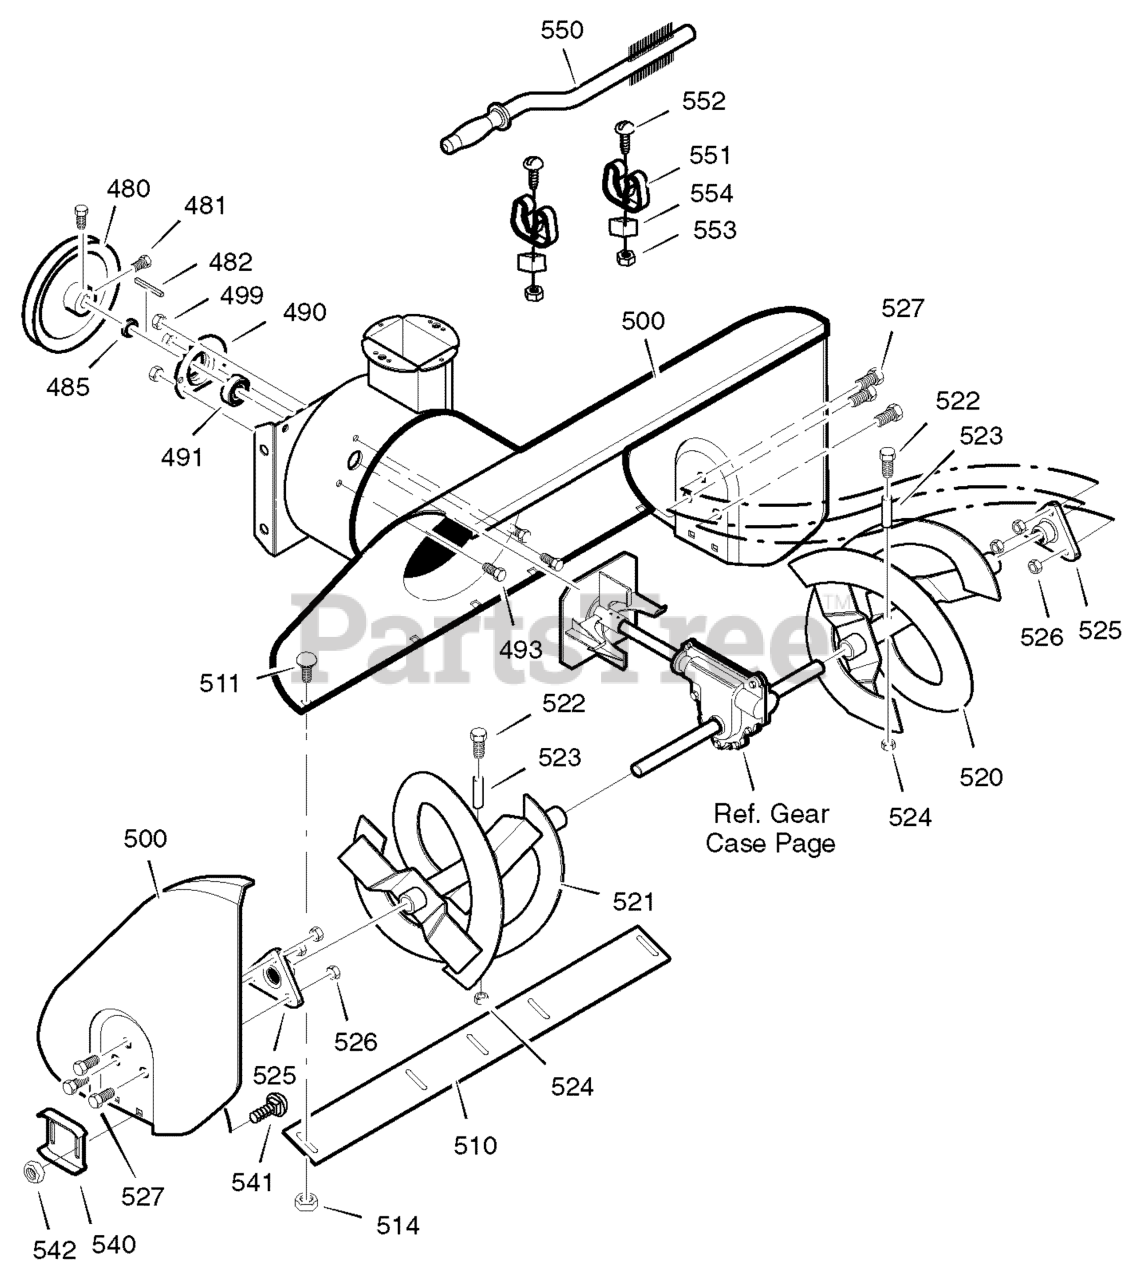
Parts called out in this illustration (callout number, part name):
480	PULLEY, V4L 6.12X0.67
481	SCREW, 5/16-18 x 0.63
482	KEY, SQUARE 3/16 X 3/4
485	SPACER, FRICTION PULLEY
490	RETAINER, BALL BRNG
491	BEARING, BALL
493	BOLT, HEX 5/16-18 X 1/2
499	NUT, 5/16-18 HEXWDFLLK
500	HOUSING, ASSY
510	BLADE, SCRAPER
511	BOLT, 1/4-20 X 3/4
514	NUT, 1/4-20
520	AUGER, ASSY, LH
521	AUGER, ASSY, RH
522	SCREW
523	SPACER, SLEEVE
524	NUT, 1/4-20
525	BEARING, FLANGE
526	NUT, 5/16-18
527	SCREW, 5/16-18 x 3/4
540	SKID, HEIGHT ADJUST
541	BOLT, 5/16-18 X .75
542	NUT, 5/16-18
550	BRUSH, CLEANOUT
551	CLIP, RETAINER
552	SCREW
554	BLOCK
